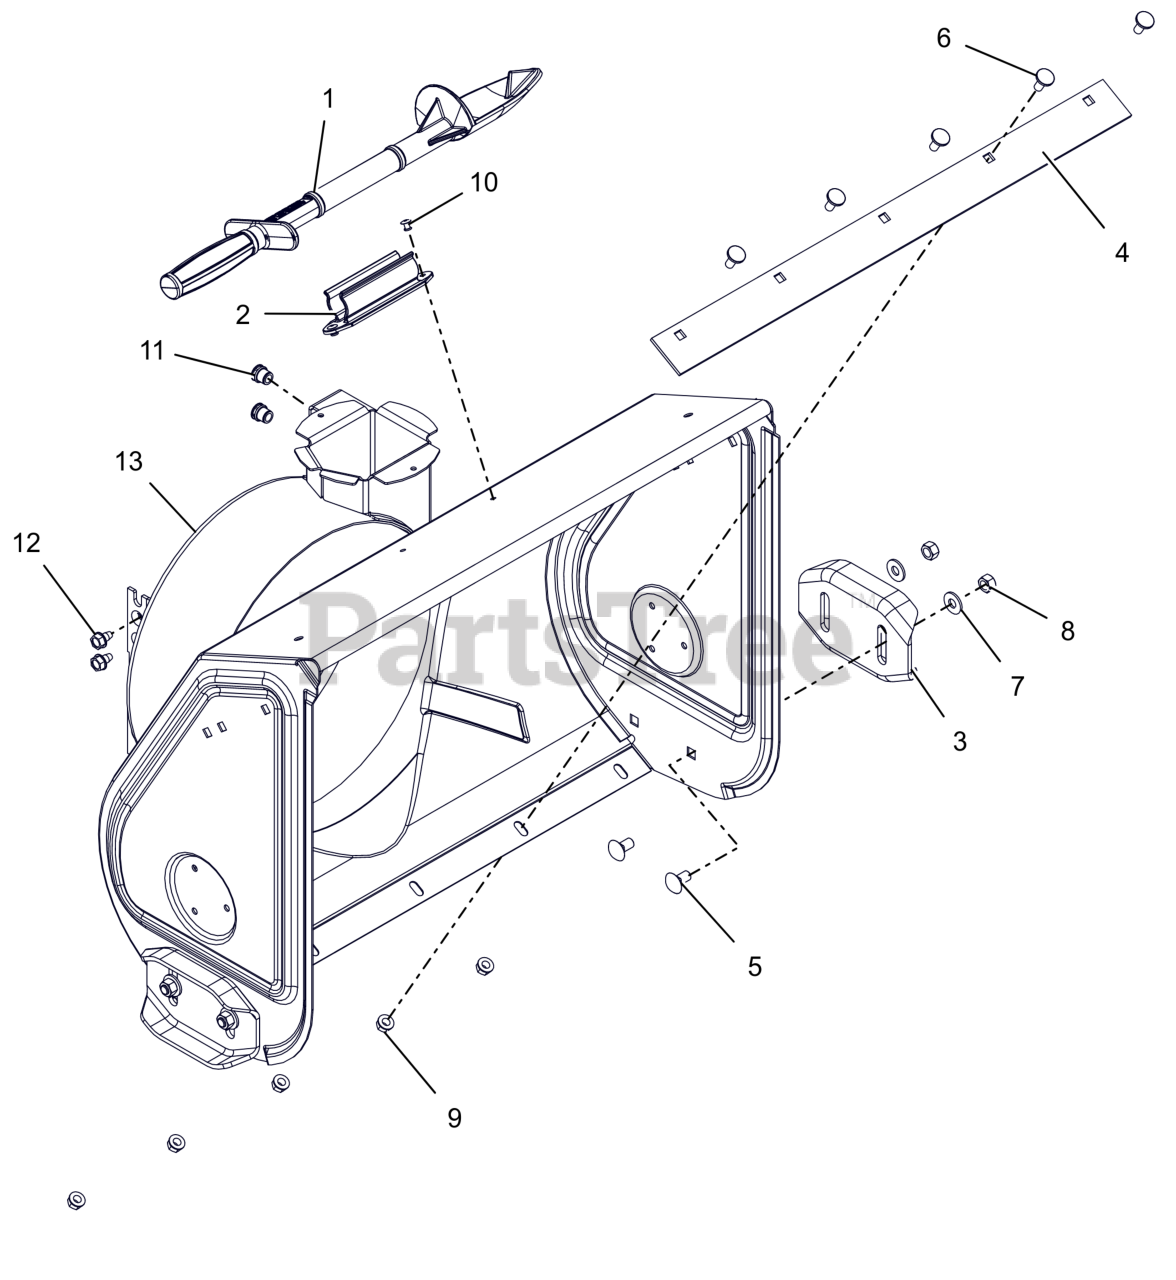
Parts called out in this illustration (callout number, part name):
1	DEVICE, SNOW CLEAN OUT
2	MOUNT, SNOW CLEAN OUT
3	SKID SHOE, REVERSIBLE - ORANGE
4	SCRAPER BLADE, 24" COMPACT HI
5	BLT, RHSSN .38-16X.75 G5 ZCC
6	BOLT, MODIFIED HEAD CARRIAGE
7	WSHR,FLT .375X.875X.083 ZCC
8	NUT-LK-CTR .38-16 ZC120
9	NUT-LK-TOP-FLG .312-18 GF ZCC
10	RVT, POP .1875 ZCC
11	NUT,THD,INSERT .38-16 ZC120
12	SCR,TAP .312-18X.50 HWH TR ZCC
13	BLOWER HOUSING, 24" HI ORANGE
